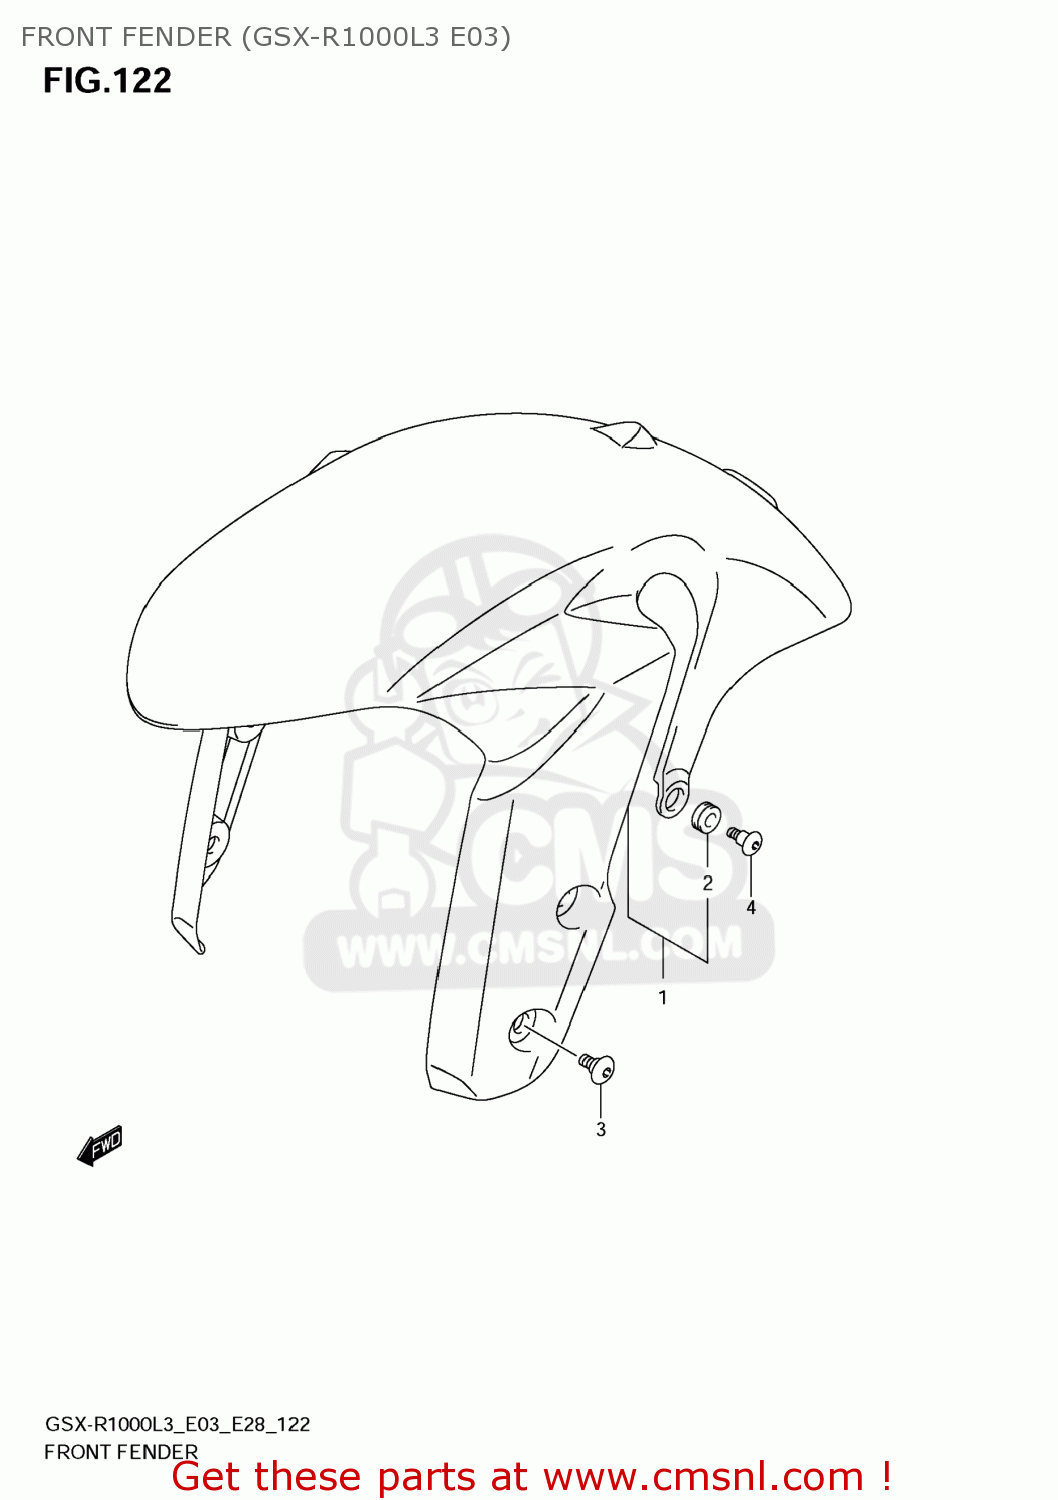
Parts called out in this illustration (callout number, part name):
1	FENDER ASSY,FR(BLUE)
2	CUSHION
3	SCREW(6X16)
4	SCREW(6X16)
